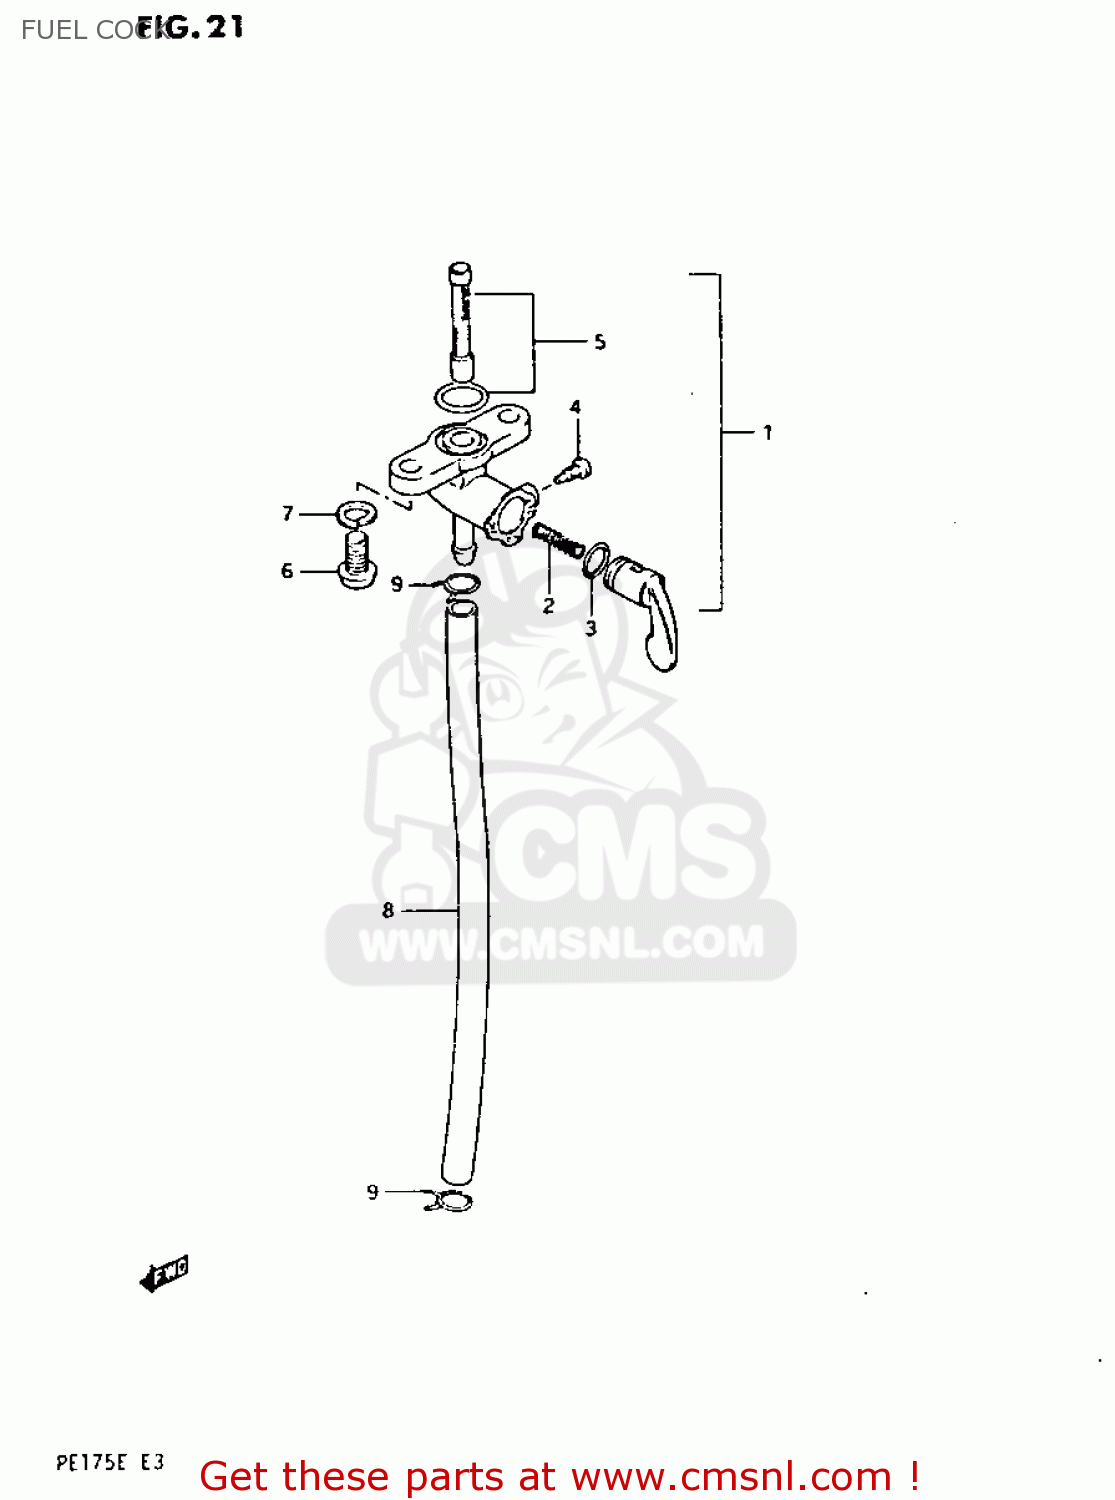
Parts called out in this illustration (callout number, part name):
1	COCK ASSY,FUEL
2	SPRING,FUEL COCK VALUE
3	O RING,LEVER
4	SCREW
5	FILTER SET FUEL
6	SCREW
7	WASHER,LOCK
8	HOSE
9	CLIP
